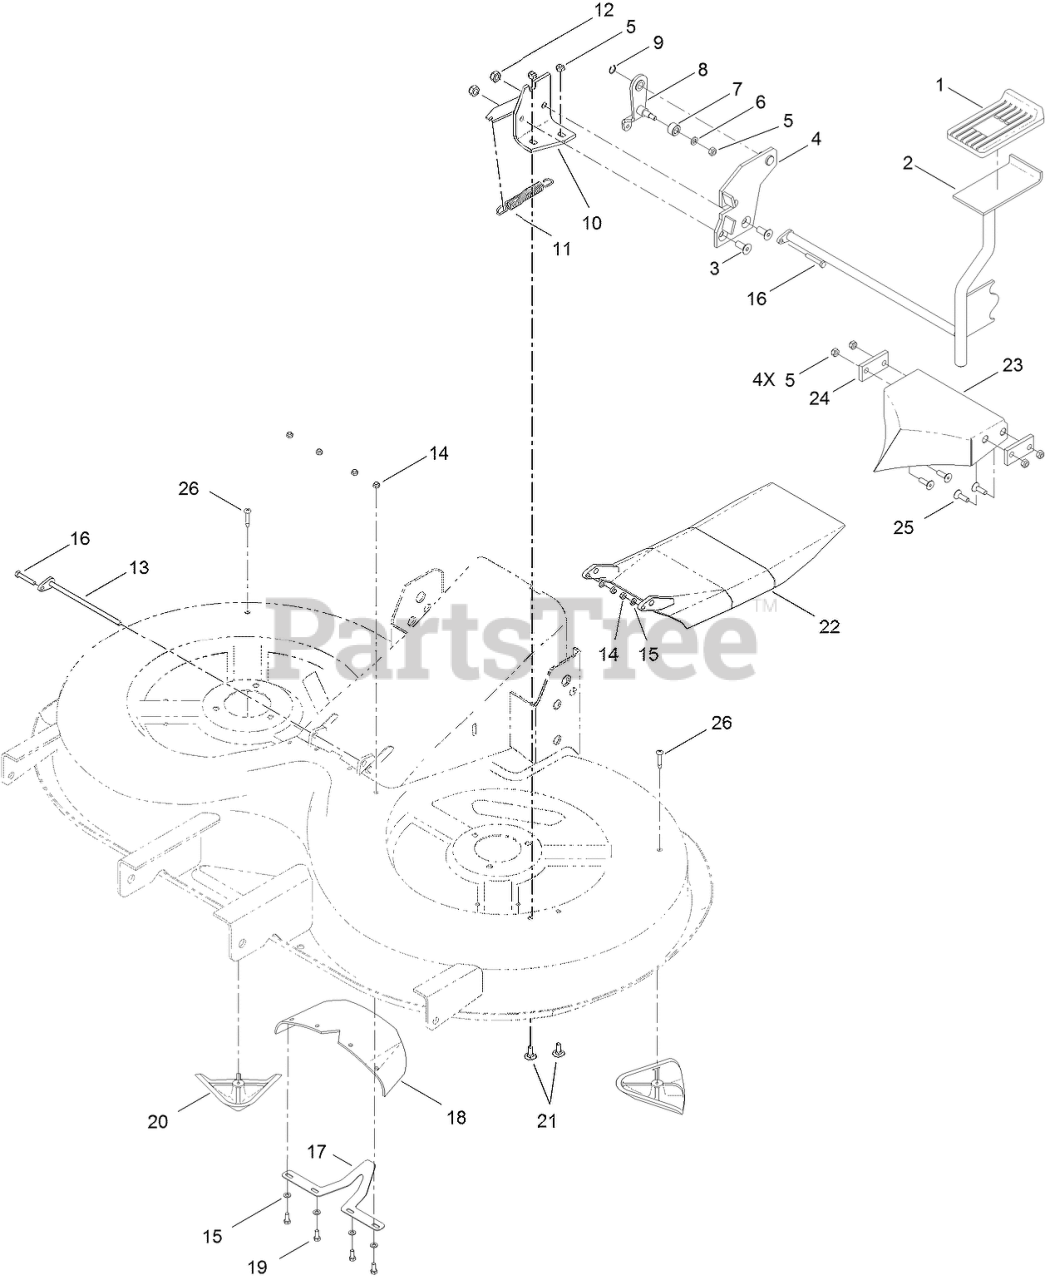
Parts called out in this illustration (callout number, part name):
1	Cover-Lever, FOOT
2	Lever-Foot
3	SCREW-HSFH
4	Plate-Stop
5	NUT-LOCK
6	WASHER-FLAT
7	Roller
8	Lever-Spring
9	RING-LOCKING
10	Bracket-Mounting
11	Spring
12	NUT
13	Rod-Door, Mulch
14	NUT-LOCK
15	WASHER
18	Gasket-Door, Mulch
19	Screw-HH
20	Kicker
21	SCREW-CARR
22	DOOR-MULCH
23	Baffle-Center
24	PLATE-BAFFLE, CENTER
26	SCREW-TAP, PPH
